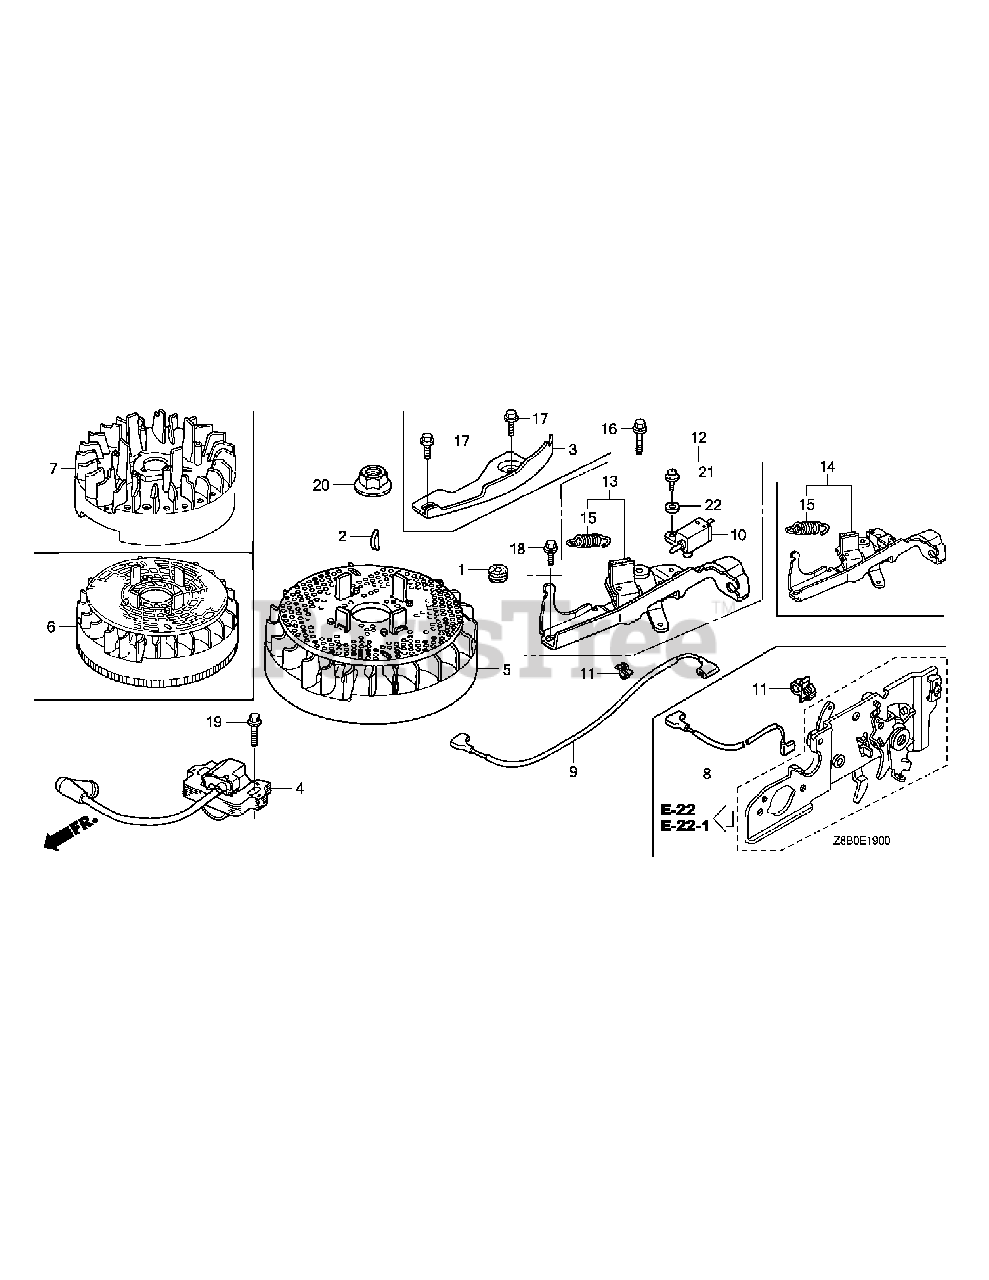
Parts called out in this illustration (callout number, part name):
1	GROMMET A, RR. COVER (Honda Code
1	GROMMET A, RR. COVER (8X16X8) (Honda Code
2	KEY, SPECIAL WOODRUFF (25X18) (Honda Code
4	COIL ASSY., IGNITION
5	FLYWHEEL ASSY.
9	WIRE, STOP SWITCH
10	SWITCH ASSY., ENGINE STOP (Honda Code
11	HOLDER, WIRE
11	CLIP A, CABLE (NIFCO)
13	BRAKE SUB-ASSY.
15	SPRING, BRAKE LEVER
16	BOLT, FLANGE (6X23)
18	BOLT, FLANGE (6X14) (CT200) (Honda Code
19	BOLT, FLANGE (6X20) (CT200) (Honda Code
20	NUT, SPECIAL (14MM)
21	SCREW-WASHER (4X12) (Honda Code
22	WASHER, PLAIN (4MM)
